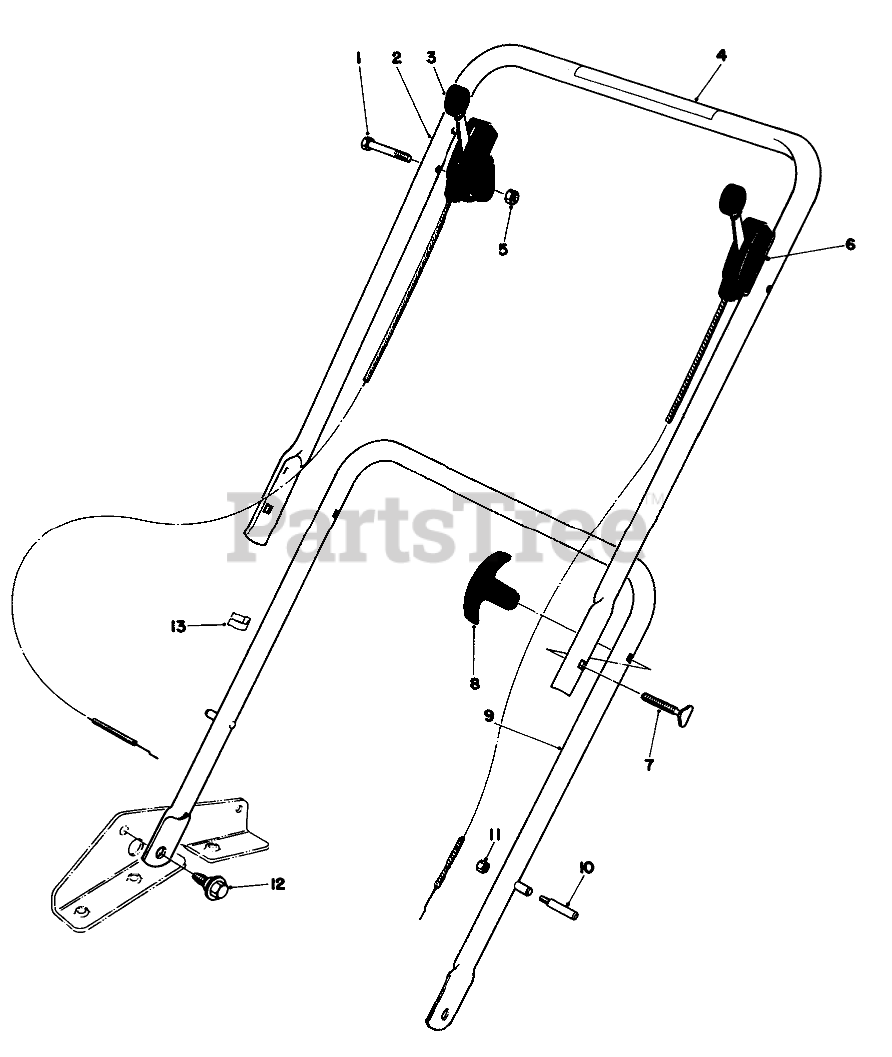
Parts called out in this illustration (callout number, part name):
1	SCREW-HH
2	Upper Handle
3	Throttle Control
4	Decal
5	NUT-LOCK
6	Traction Control
7	HANDLE SCREW
9	LOWER HANDLE ASM SP
10	HANDLE PIN
11	Nut
12	SCREW-SHOULDER
